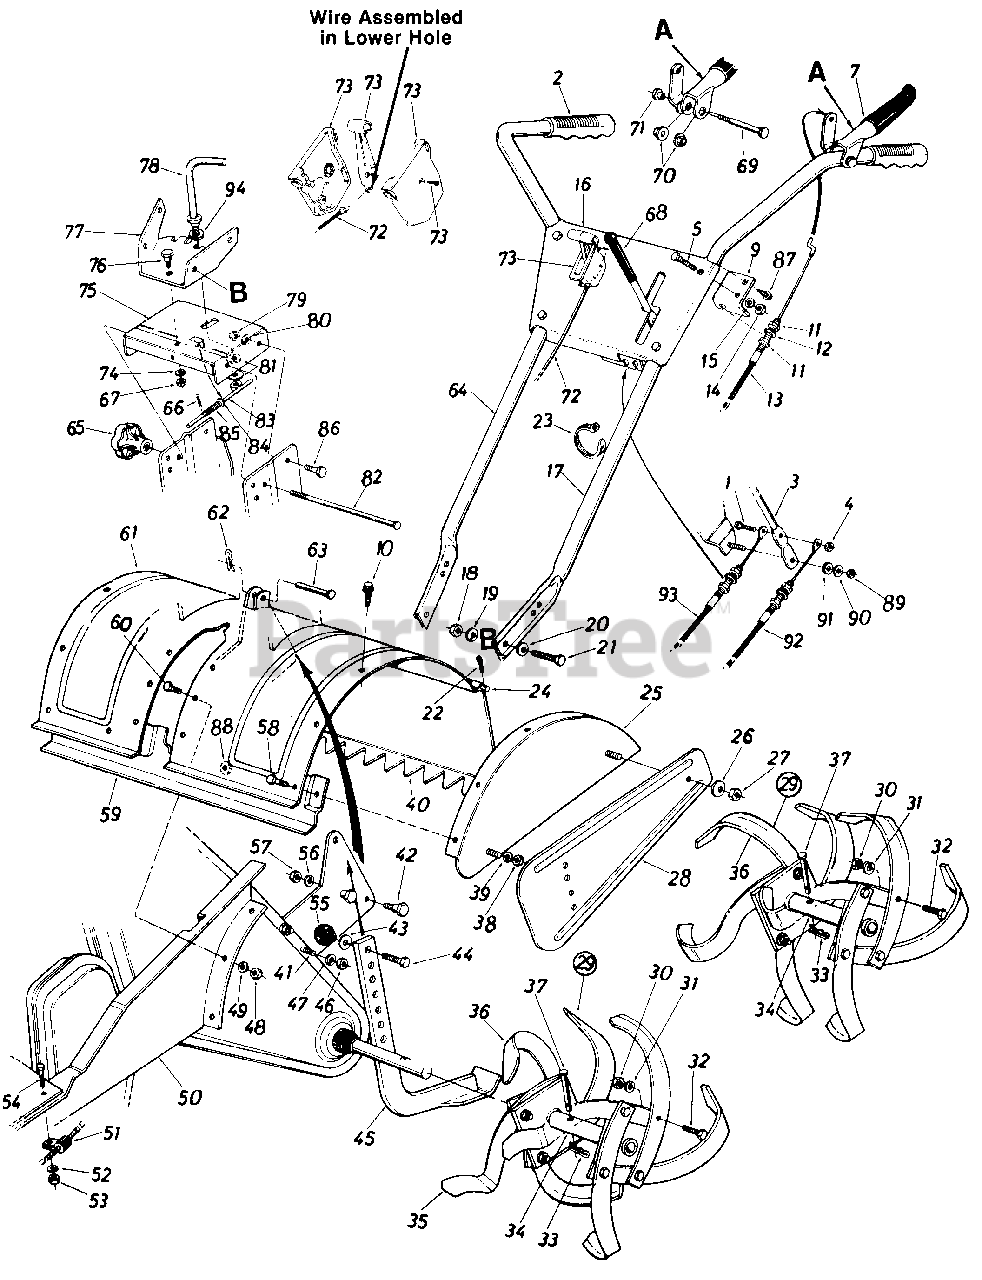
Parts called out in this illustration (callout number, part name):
1	Hex Bolt 1/4-28 x 1.0" Lg.
2	Grip
3	Clutch Lever
4	Hex Cent. L-Nut 1/4-28 Thd.
5	Carr. Bolt 5/16-18 x 1.75"
7	Clutch Grip Ass'y.-L.H.
9	Clutch Cable Bracket
10	Hex Wash. S-Tap Scr. 5/16-18 x .62" Lg.
11	Hex Nut 5/16-24 Thd.
12	L-Wash. 5/16" I.D.
13	Clutch Control Cable
14	Hex Nut 5/16-18 Thd.
15	L-Wash. 5/16" I.D.
16	Handle Panel Ass'y.
17	Handle-L.H.
18	Hex Nut 3/8-16 Thd.
19	L-Wash. 3/8" I.D.
20	Bell-Wash. 3/8" I.D.
21	Hex Bolt 3/8-16 x 1.00" Lg.
22	Cotter Pin 3/32" Dia. x 3/4"
23	Cable Tie
24	Tiller Flap Rod
27	Hex Nut 5/16-18 Thd.
31	L-Wash. 3/8" I.D.
32	Hex Bolt 3/8-24 x 1.25" Lg.
33	Hairpin Cotter
38	Hex Nut 5/16-18 Thd.
39	L-Wash. 5116" I.D.
41	Hex Bolt 5/16-18 x 1.0" Lg.
42	Shld. Bolt 1/2" Dia. x .426"
43	Fl-Wash. 3/8" I.D. x 5/8" O.D.
44	Hex Bolt 3/8-16 x 3/4" Lg.
46	Hex Nut 5/16-18 Thd.
47	L-Wash. 5/16" I.D.
48	Hex Nut 5/16-18 Thd.
49	L-Wash. 5/16" I.D.
52	L-Wash. 5/16" I.D.
53	Hex Nut 5/16-18 Thd.
54	Hex Bolt 5/16-18 x 3/4" Lg.
55	Ball Knob 1-1/4" Dia.
56	L-Wash. 3/8" I.D.
57	Hex Nut 3/8-16 Thd.
58	Hex Bolt 5/16-18 x .75" Lg.
63	Clevis Pin 3/8" Dia.
64	Handle-R.H.
65	Hand Knob
66	Cotter Pin 1/16" Dia. x .75"
67	Hex Cent. L-Nut 3/8-16 Thd.
68	G ri p
69	Shoulder Bolt .375" Dia. x 1.37" Lg.
70	Hex Flange Plastic Bearing
71	Shoulder Nut 1/4-20 Thd.
72	Throttle Control Wire
73	Throttle Control Box Ass'y.
74	Bell-Wash. .40" I.D. x 1.13"
79	Hex Cent. L-Nut 3/8-16 Thd.
80	Bell-Wash. .40" I.D. x .88"
81	Bell-Wash. 1/2" I.D. x 1.00"
82	Lock Pin 5116" Dia. x 8"
83	Lower Sliding Ass'y.
84	Fl-Wash. .291" I.D. x .62"
85	Compression Spring .36" O.D. x 1.00" Lg.
86	Shoulder Bolt 1/2" Dia. x .170" Lg.
87	Hex Wash. S-Tap Scr. 1/4-20 x.50" Lg.
88	Bell-Wash. 5116" I.D.
89	Hex Cent. L-Nut 5/16-18 Thd.
90	Fl-Wash. .344" I.D. x .87"
91	Rubber Wash. .33 I.D. x .87 "
92	Control Cable
93	Control Cable
94	Fl-Wash. .62" I.D. x 1.57"
14979-0498	Rear Tine Shield - OLD CUB YELLOW (0498)
14979-0638	SHIELD-REAR TINE - MTD/TROY-BILT RED (0638)
14979-0665	SHIELD-REAR TINE - YARDMAN GREEN (0665)
